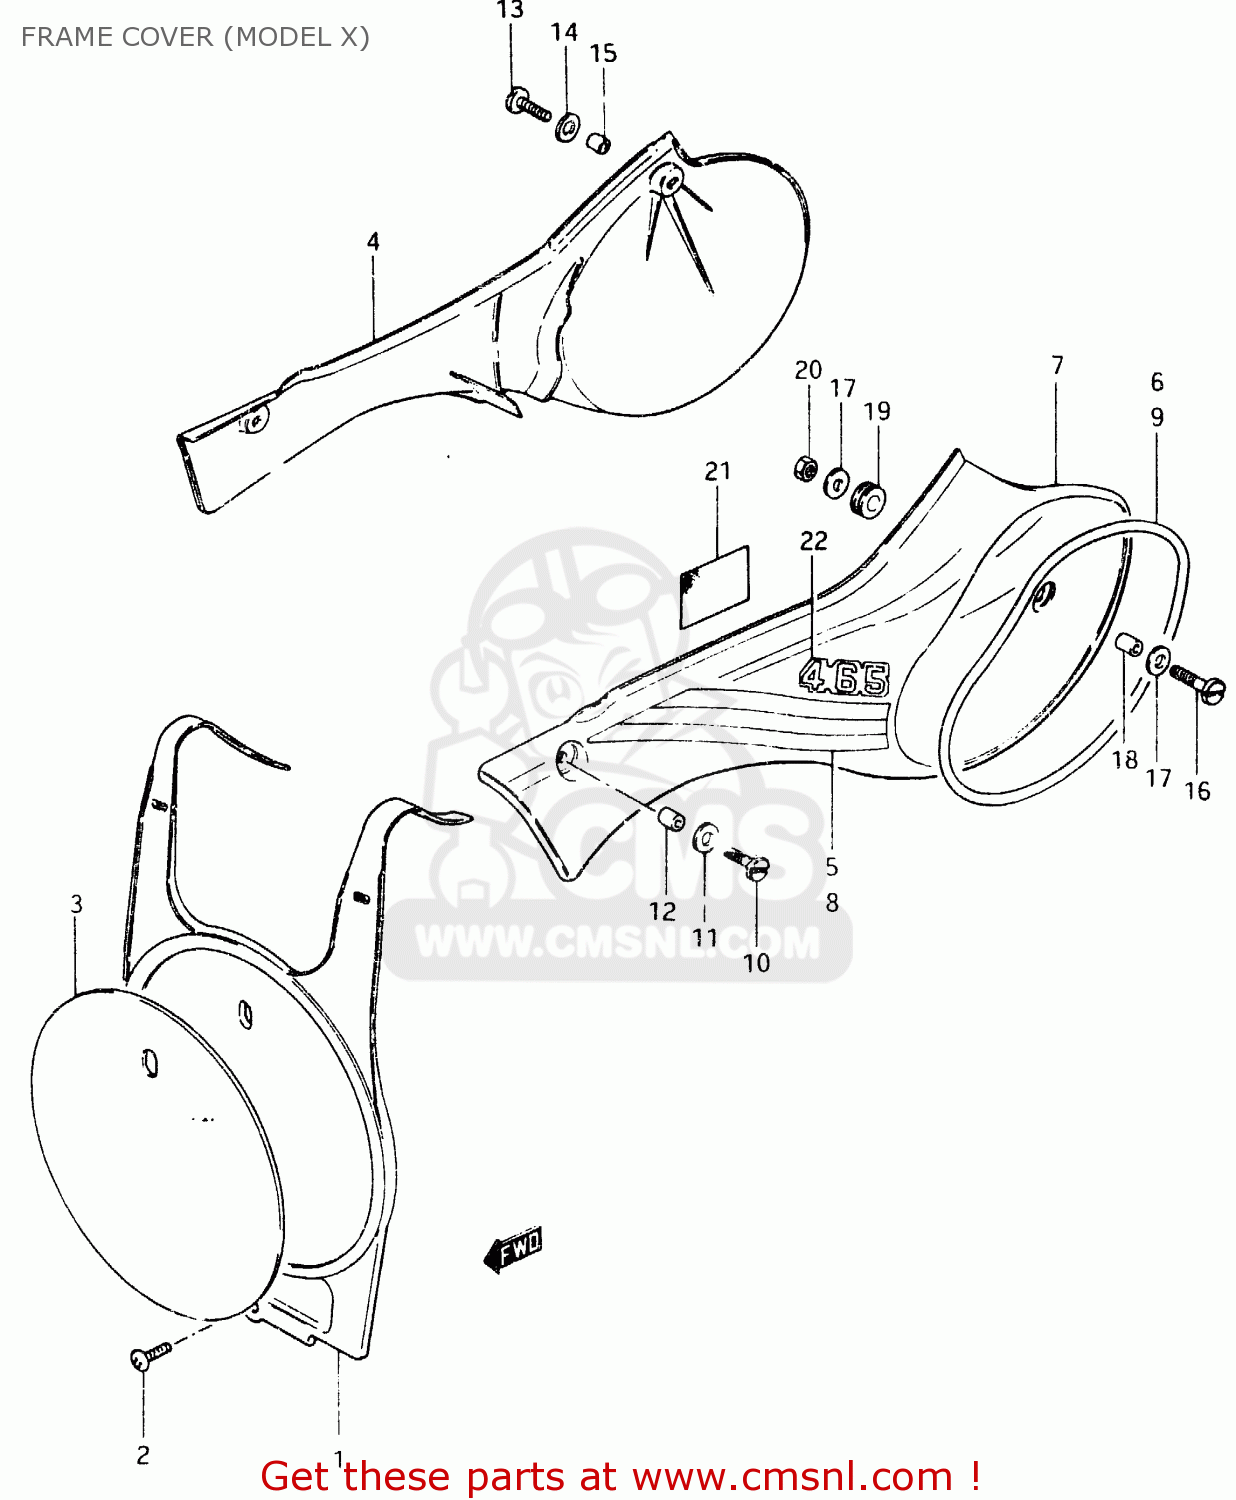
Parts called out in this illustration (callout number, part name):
1	PLATE,NUMBER,FRONT
2	(5X20) CROSS SCREW
3	EMBLEM,FRONT NUMBER PLATE
4	COVER,FRAME,RIGHT
5	TAPE, RH
6	TAPE,FRAME COVER
7	COVER,FRAME,LEFT
8	TAPE, LH
9	TAPE,FRAME COVER
10	SCREW
11	WASHER FRAME COVER
12	SPACER,FRAME COVER,FRONT
13	SCREW
14	WASHER FRAME COVER
15	SPACER FRAME COV RR
16	SCREW
17	WASHER FRAME COVER
18	SPACER,FRAME COVER,FRONT
19	CUSHION
20	NUT 6MM
21	HEAT SHIELD,FRAME COVER
22	EMBLEM
